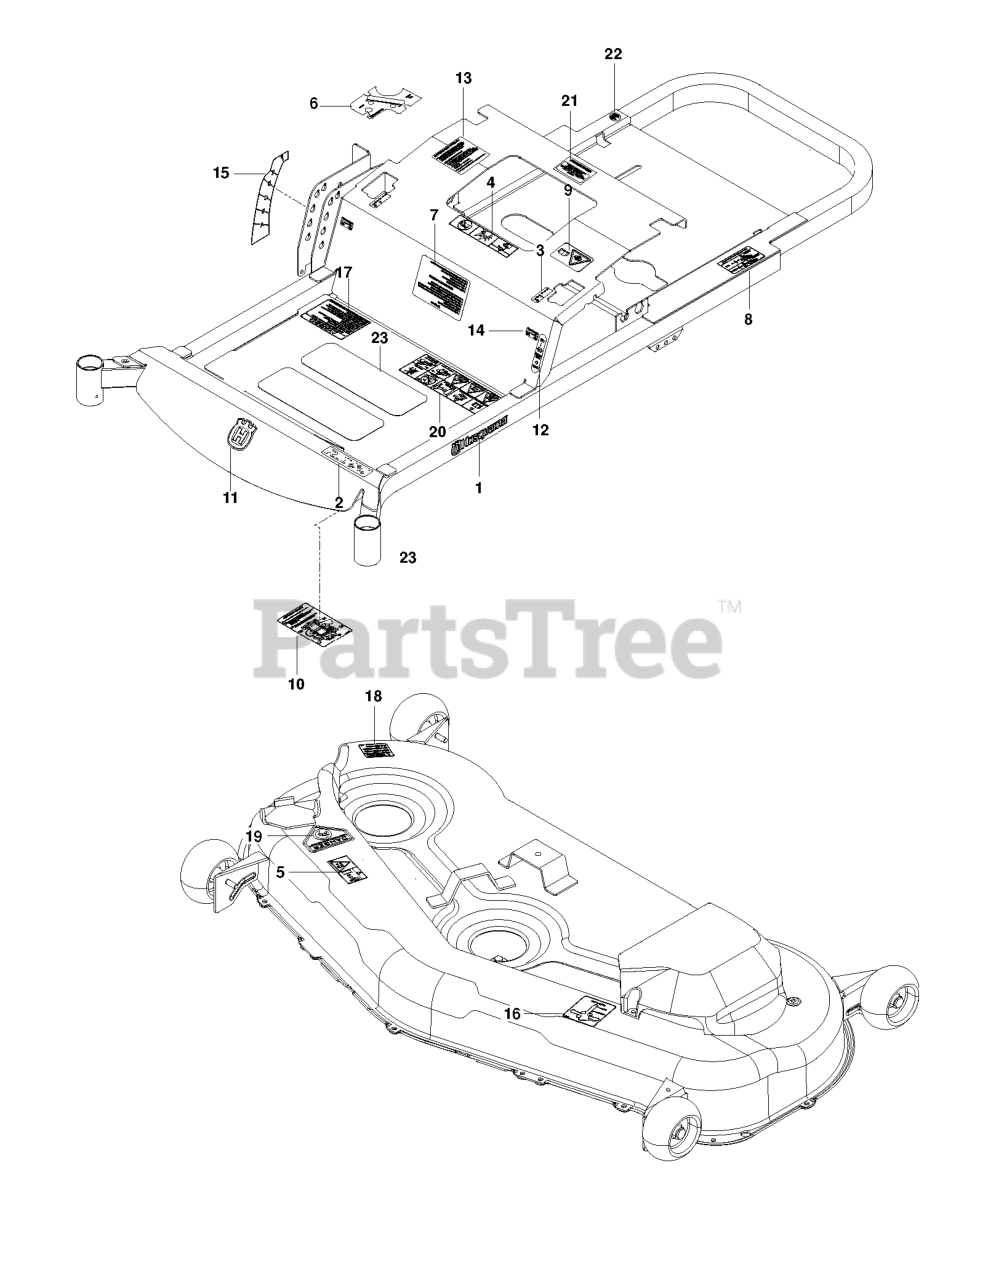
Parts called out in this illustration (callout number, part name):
1	RP.DECAL.BADGE.170MM.TEXTLOGO
2	DECAL, RZ5426
3	DECAL, MOTION CONTROL
4	EURO DECAL-BATTERY WARNIN6
5	DECAL, EURO SEVERING
6	DECAL, CTRL PANEL, HUSQ
7	DECAL, START
8	DECAL, DO NOT TOW
9	DECAL, EXITING MOWER
10	DECAL, SERVICE
11	DECAL.AUGER.HUSQ.CROWN.SNOW
12	DECAL, PARK BRAKE
13	DECAL, CUSTOMER RESPNSIBILITY
14	DECAL, F.S.T.
15	DECAL, DECK HEIGHT, HUSQ
16	DECAL, BELT ROUTING
17	DECAL, WARNING
18	DECAL, CAUTION
19	DECAL, CPSC
20	DECAL, SAFETY WARNING
21	DECAL.FENDER
22	DECAL.E85.WARNING.2012
23	ANTI-SKID PAD
